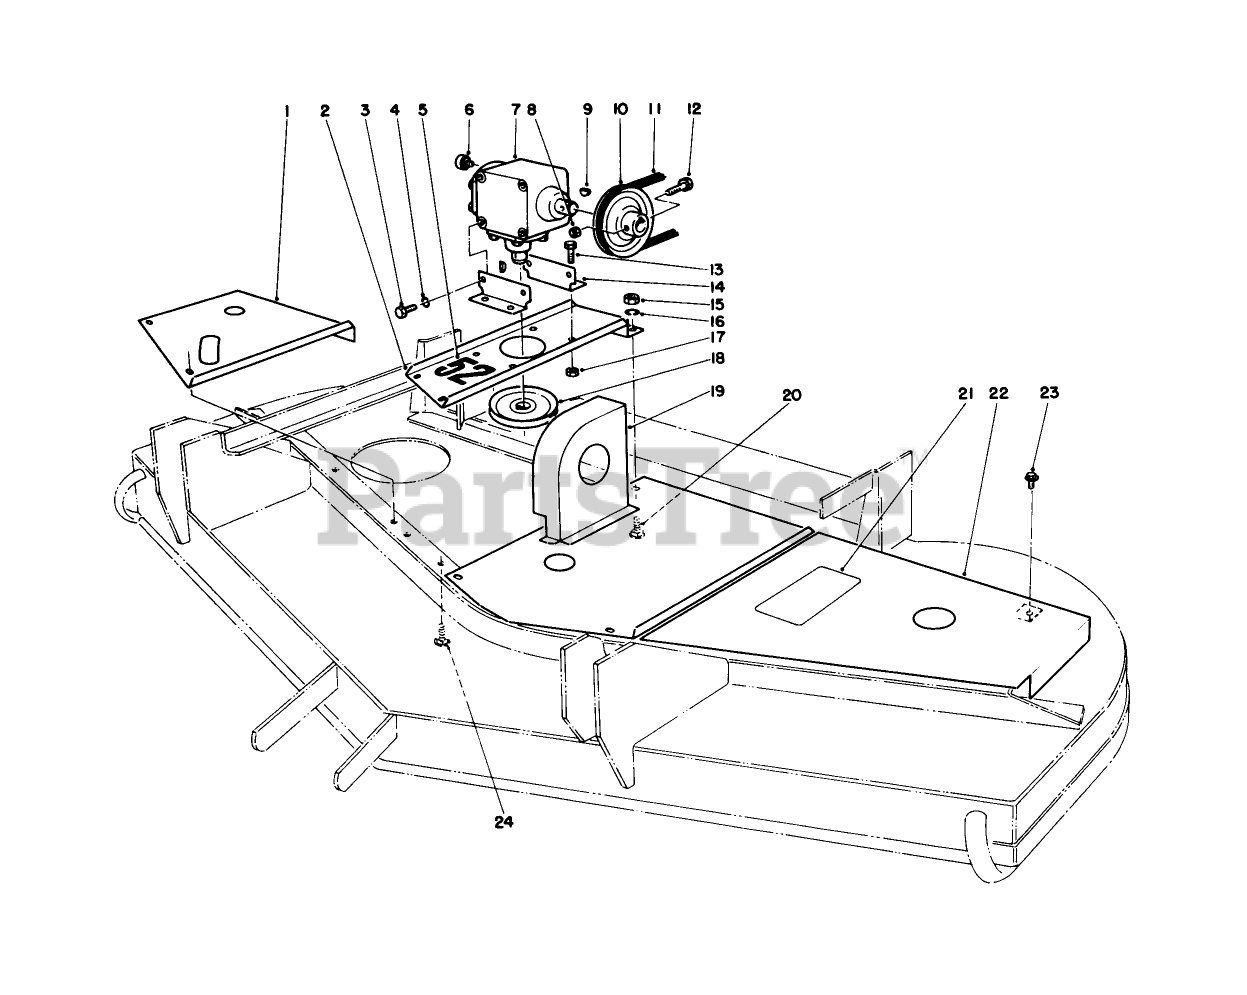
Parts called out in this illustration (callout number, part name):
3	SCREW-HH
4	WASHER-LOCK
5	DECAL
6	FITTING-LUBE
8	NUT-LOCK, NI
11	V-BELT, DECK
12	SCREW-HH
13	SCREW-HH
15	NUT-HEX
16	WASHER-LOCK
17	NUT-LOCK, NI
20	BOLT-CARR
23	SCREW-HHFTF
24	SCREW-CARR
